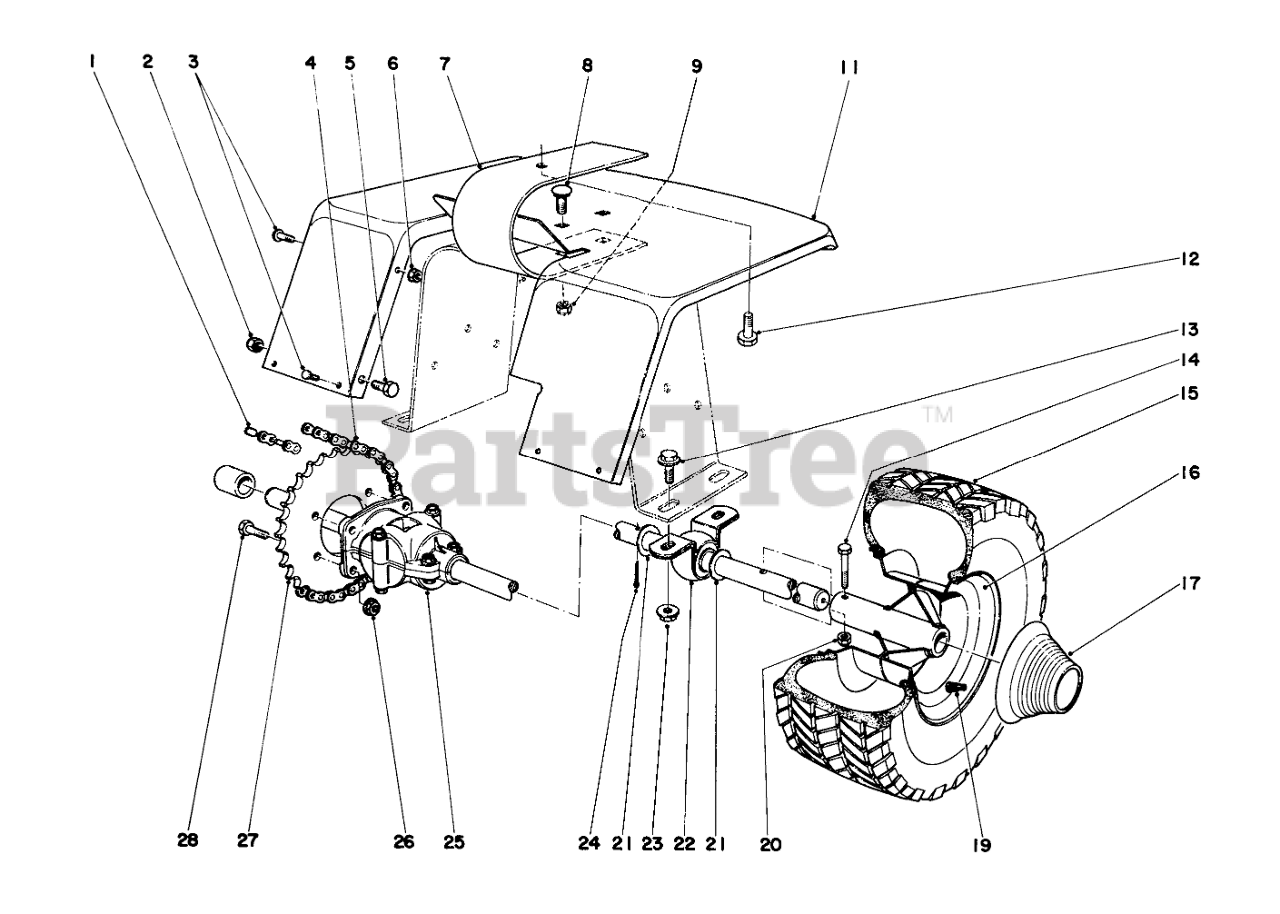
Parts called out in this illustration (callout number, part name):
1	1/4 OFFSET LINK
2	NUT-LOCK, CONE
3	10-24 X 3/8 PAN HD SC
4	Chain
5	SCREW-HH
6	NUT-KEPS
7	Seat Spring
8	BOLT-CARR
9	NUT-LOCK, CONE
11	Fender
12	Capscrew
13	SCREW-HHF
14	SCREW-HH
15	Tire Turf King
17	Hub Cap-Rear
19	STEM-VALVE
20	NUT-LOCK, SIDE
21	WASHER
22	PILLOW BLOCK
23	NUT-HF
24	PIN-COTTER
25	Differential
26	NUT-HF
27	Sprocket
28	SCREW-HH
